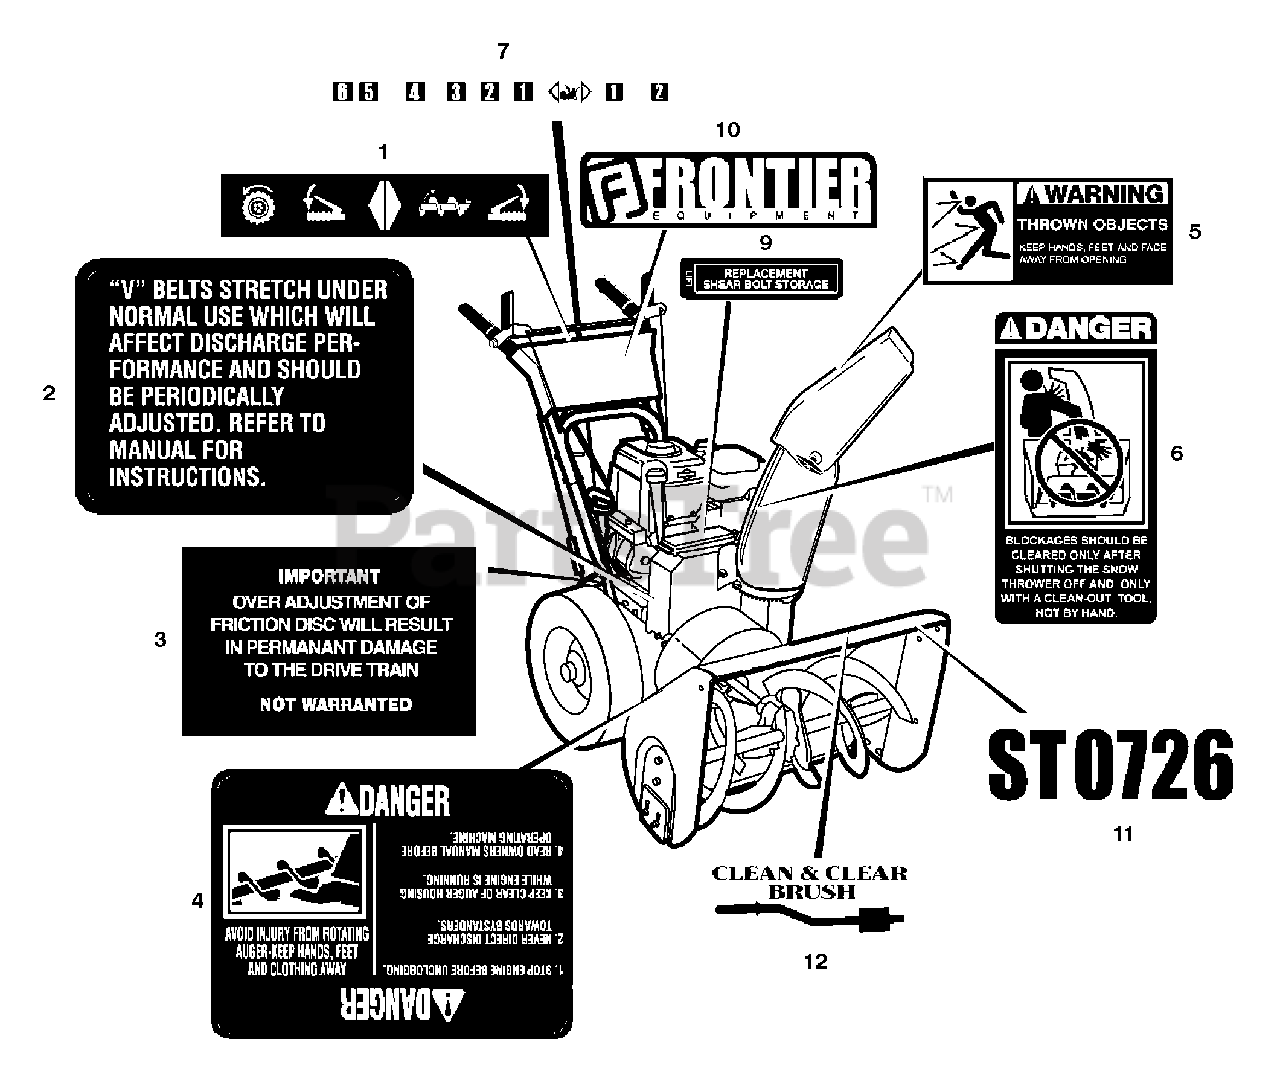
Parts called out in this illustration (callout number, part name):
1	DECAL, HAND CONTROL
2	DECAL, V-BELTS
3	DECAL, OVER ADJUSTMENT
4	DECAL, ROTATING AUGER
5	DECAL, THROWN OBJECTS
6	DECAL, UNCLOGGING CHUTE
7	DECAL, SPEED CONTROL
9	DECAL, SHEAR BOLTS
10	LOGO NAMEPLATE, FRONTIER
11	DECAL, ST0726
12	DECAL, CLEAN & CLEAR BRUSH
